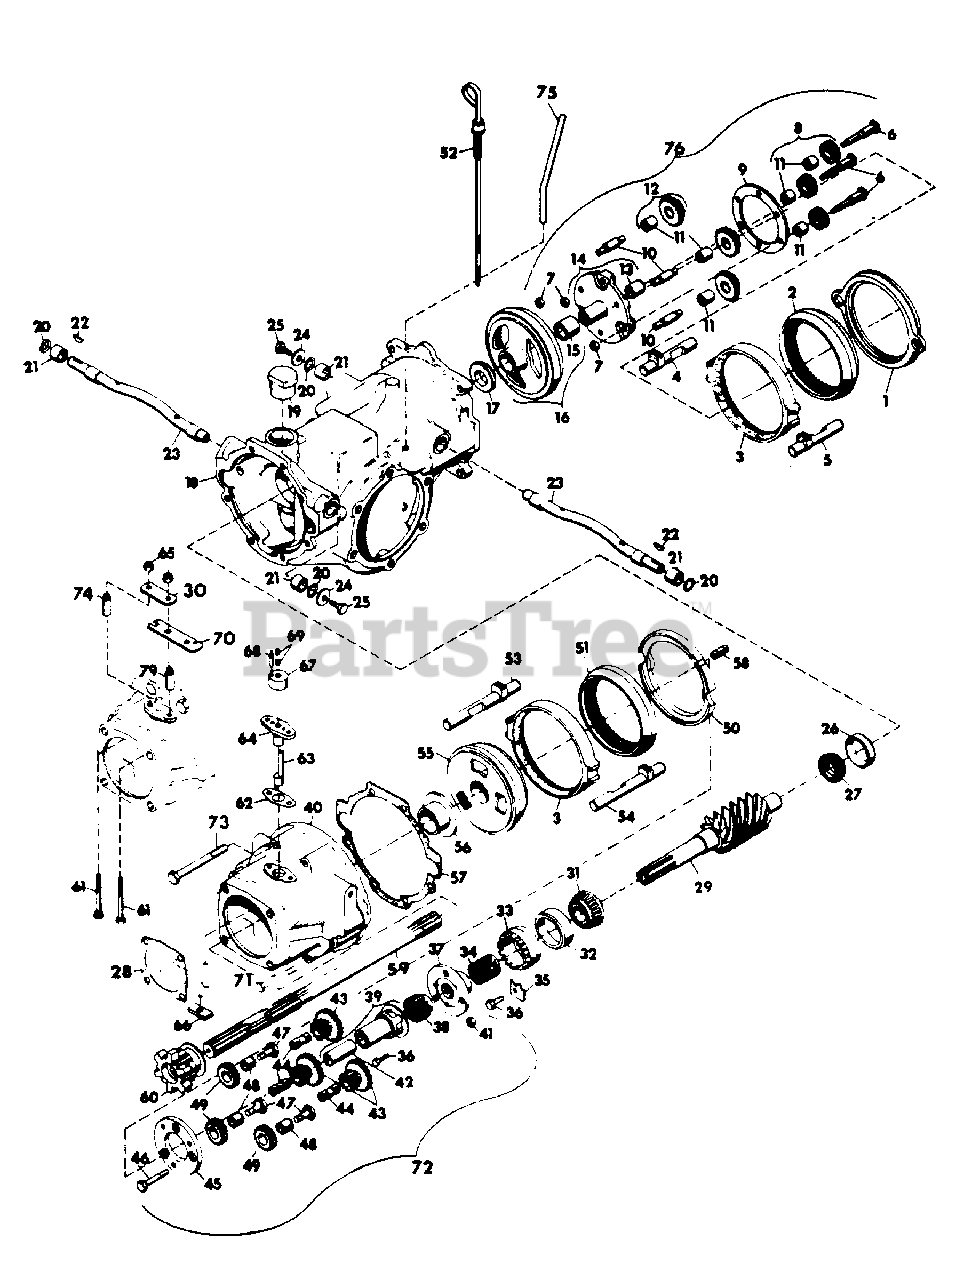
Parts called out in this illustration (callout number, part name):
1	SPACER, REAR
2	GEAR, REAR RING
3	ASSEMBLY, CLUTCH CUP
4	ROD, REAR CLUTCH SLIDE L.H.
5	ROD, REAR CLUTCH SLIDE R.H.
6	BOLT, ORBIT GEAR
7	NUT, LOCK 5/16-18 L.H. THD.
8	ASSEMBLY, EXTERNAL ORBIT GEAR
9	SPACER, PIN
10	PIN, HI-LO ORBIT GEAR
11	BUSHING .501X.627X.495
12	ASSEMBLY, INTERNAL ORBIT GEAR
13	BUSHING, .737X.877X.682
14	ASSEMBLY, PLANET GEAR CARRIER
15	BUSHING, 1.231X1.502X1.312
16	ASSEMBLY, RING GEAR AND BUSHING
17	PLATE, REAR THRUST
18	CHASSIS
19	PLUG, OIL FILTER
20	O-RING, .750X1.00
21	BUSHING, .750X1.002X.625
22	KEY, WOODRUFF .125X.625 HARD
23	SHAFT, ACTUATING
24	WASHER, FLAT .265X1.250X.063
25	BOLT, HEX 1/4-20X.50
26	CUP, ROLLER BEARING
27	CONE, ROLLER BEARING
28	GASKET, ATTACHMENT
29	WELDMENT, WORM SHAFT ASM 8 LEAD
30	SPACER, STRAP
31	CONE, ROLLER BEARING
32	CUP, ROLLER BEARING
33	NUT, BEARING ADJUSTMENT
34	SPACER, SPRING PIN PLATE
35	NUT, ADJUSTMENT
36	BOLT, HEX 1/4-20X.625
37	PLATE, FRONT PIN
38	GEAR, SUN PINION
39	ASSEMBLY, QUILL AND BUSHING
40	CASTING, ADVANCE
41	NUT, HEX 1/4-20
42	BUSHING, .875X1.000X2
43	GEAR, ORBIT
44	PIN, FWD-REV ORBIT GEAR
45	SPACER, FRONT PIN
46	BOLT, SPACER
47	BOLT, REVERSE IDLER
48	BUSHING, .375X.685X.516
49	GEAR, REVERSE IDLER
50	CUP, GEAR
51	GEAR, INTERNAL
52	ASSEMBLY, DIP STICK
53	ROD, CLUTCH SLIDE L.H.
54	ROD, CLUTCH SLIDE R.H.
55	CONE, REVERSE GEAR
56	ASSEMBLY, THRUST BUSHINGS
57	GASKET, CHASSIS FRONT
58	PIN, ROLL
59	SHAFT, PINION
60	DOG, ATTACHMENT
61	BOLT, HEX 5/16-18X2.25
62	GASKET, SHIPPER SHAFT
63	SHAFT, SHIPPER
64	GUIDE, SHIPPER SHAFT
65	NUT, LOCK 5/16-18
66	BLOCK TRUNNION
67	BODY, SHIPPER SHAFT
68	PIN, SPRING .25X.75
69	SCREW, SET 3/8-16X.25
70	ARM, SHIFTER
71	BOLT, HEX 5/16-18X3.50
72	ASSEMBLY, FWD-REV PLANETARY
73	BOLT, HEX 5/16-18X3.25
74	SPACER, SHIPPER SHAFT GUIDE
75	GUIDE, DIPSTICK
76	ASSEMBLY, HI-LO PLANETARY
